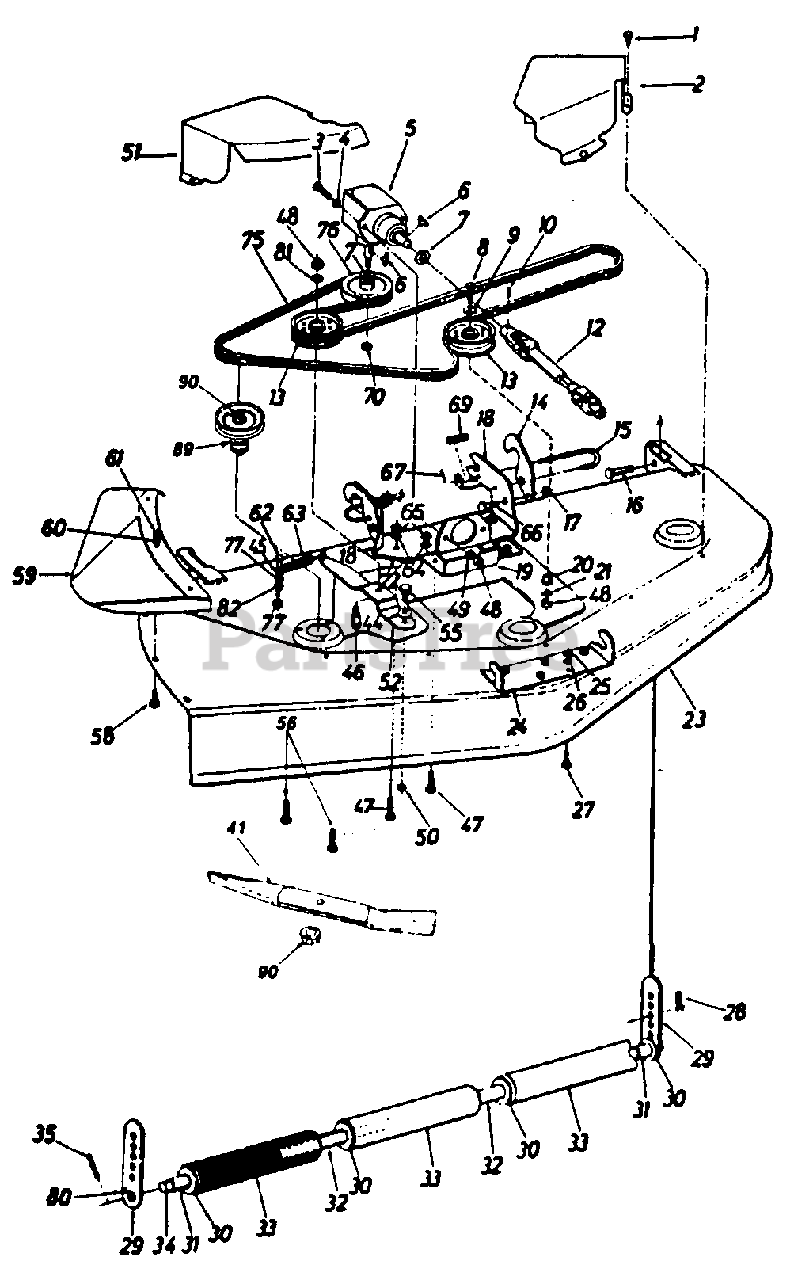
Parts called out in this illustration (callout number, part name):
1	Hex TT-Tap Scr. 1/4-20 x .5" Lg.
3	Hex Bolt 3/8-16 x 1.25" Lg.
4	Ext. L-Wash. 3/8" I.D.
5	Right Angle Drive
6	#9 Hi-Pro Key 3/16 x 3/4" Dia.
7	Fl-Wash. 29/32" I.D.
8	Hex Bolt 3/8-16 x 2.25" Lg."
9	Fl-Wash. 3/8" I.D.
10	Sq. Hd. Set Scr. 3/8-16 x .50"
12	Universal Drive Shaft Ass'y.
13	Deck Idler Pulley
14	Hanger Lock
16	Clevis Pin .50" Dia.
17	Hex L-Nut 5/16-18 Thd.
21	L-Wash. 3/8" I.D.
26	L-Wash. 5/16" I.D.
27	Carriage Bolt 5/16-18 x .75" Lg.
28	Internal Cotter Pin
30	Fl-Wash. .75" I.D. x 1.5" O.D.
31	Spacer .758" I.D. x 1.25" O.D. x .530
34	Roller Shaft
35	Roll Pin 3/16 x 1.25"
41	Blade 17" Star Blade
44	Spr. Wash. .445" I.D.
45	Fl-Wash. 1/4" I.D.
46	Shld. Bolt .625" Dia. x .96"
47	Carriage Bolt 5/16-18 x 1.5" Lg.
48	Hex Nut 3/8-16 Thd.
49	L-Wash. 3/8" I.D.
50	Hex L-Nut 7/16-14 Thd.
56	Hex Wash. HD Tap Scr. 5/16-18 x.75" Lg.
58	Carriage Bolt 5/16-18 x .75" Lg.
60	L-Wash. 5/16" I.D.
61	Hex Nut 5/16-18 Thd."
62	Hex Bolt 1/4-28 x 1-3/4" Lg.
63	Extension Spring
64	L-Wash. 5/16" I.D.
65	Hex Nut 5/16-18 Thd.
67	Roll Pin 1/8" Dia.
69	Compression Spring
70	Hex L-Nut 5/8-18 Thd.
75	"V"-Belt
76	Drive Pulley
77	Hex L-Nut 1/4-28 Thd.
80	Spring Pin Spiral 1/4" Dia. 1.00" Lg.
81	Bell-Wash. 3/8" I.D. x .87" O.D.
82	L-Wash. 1/4" I.D.
89	Spindle Ass'y
90	Hex Flange nut 5/8-18 Thd.
